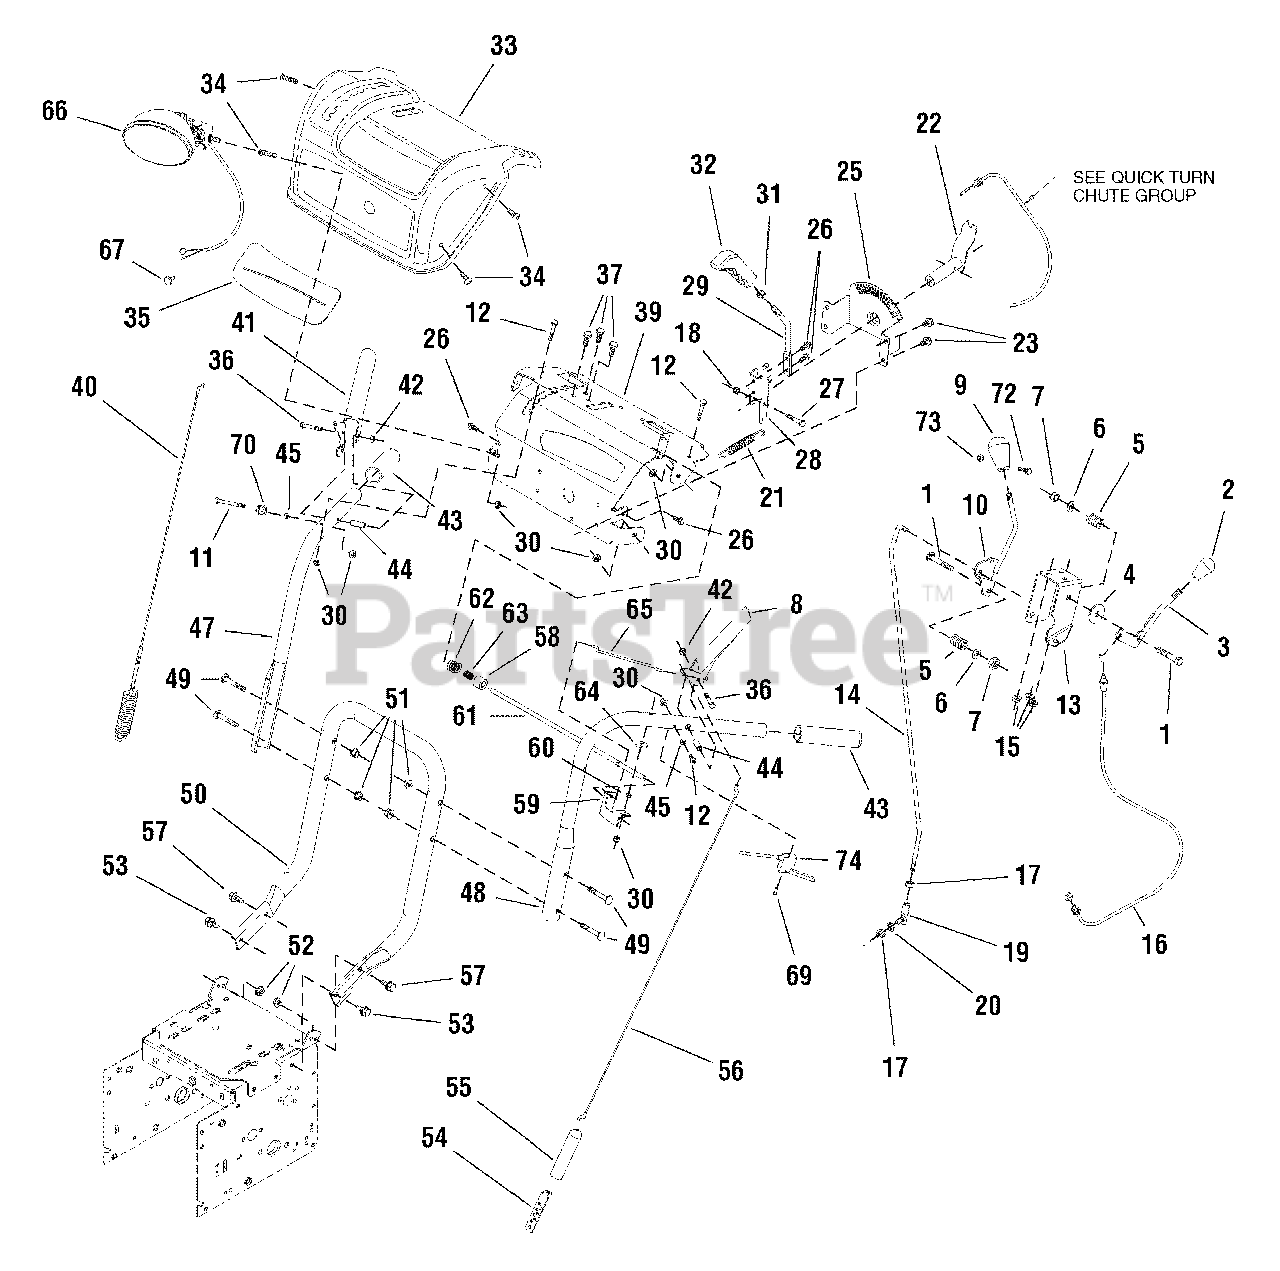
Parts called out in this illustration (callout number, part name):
1	CAPSCREW, Hex Head 3/8-16 x 2 G5
2	KNOB, Interior Thread 3/8-16
3	ROD, 3/8 Diameter 5" Large, 3/8-16 x 1 Chute
4	WASHER, 3/8
6	WASHER, 3/8
7	NUT, Hex Lock ESNA Light 3/8-16
8	HANDLE, Clutch L.H.
9	KNOB, Slot Speed
10	ROD & PLATE ASSEMBLY, Speed Control
11	CAPSCREW, Hex Head 1/4-20 x 2-1/2 G5
12	CAPSCREW, Hex Head 1/4-20 x 1-3/4 G5
13	BRACKET, Trac & Deflector Control
14	ROD
15	NUT, Hex Flange 5/16-18, Whiz Lock Small
16	CABLE, Deflector Control
17	NUT, Hex 5/16-24
18	NUT, Hex Flange 1/4-20 Centerlock Large
19	BALLJOINT, Steel
20	LOCKWASHER, Spring 5/16
21	SPRING, Extension
22	TUBE & BRACKET ASSEMBLY, Cable Support
23	SCREW, Hex Washer Head Taptite 5/16-18 x 1/2
25	SUPPORT, Chute Control 14GA
26	SCREW, Hex Washer Head Taptite 1/4-20 x 5/8
27	BOLT, Shoulder 1/4-20
28	BRACKET, Support Quick Turn
30	NUT, Hex Lock ESNA Light 1/4-20
31	NUT, Hex Jam 3/8-16
32	GRIP, Lever
33	COVER, Panel
34	SCREW, Truss Head Torx Drive 1/4-20 x 3/4
35	BELLOWS, Black Rubber Quick Turn
36	CAPSCREW, Hex Head 1/4-20 x 1-1/2 G5
37	CARRIAGE BOLT, 5/16-18 x 3/4 G5
39	SUPPORT, Dash Panel Cover
40	CABLE & SPRING ASSEMBLY, Auger Drive R.H.
41	HANDLE, Clutch R.H.
42	NUT, Hex Centerlock 1/4-20
45	SPACER
47	HANDLE, Upper R.H.
48	HANDLE, Upper L.H.
49	CARRIAGE BOLT, 5/16-18 x 2-1/4 G5
50	HANDLE, Lower
51	NUT, Hex Flange 5/16-18
52	NUT, Hex Flange 5/16-18 Two-Way Lock
53	SCREW, Hex Washer Head Taptite 5/16-18 x 3/4
54	BRACKET, Cable Adjusting
55	BOOT, Spring End Cover
57	CAPSCREW, Hex Head 5/16-18 x 1 G5
58	SPACER, Powdered Metal
59	BRACKET, Free Hand Control 12GA
60	SPACER, Powdered Metal
61	ROD & SPRING ASSEMBLY, w/Pin
62	WASHER, 1/2
63	SPRING, Compression
64	WASHER, 1/4
65	ROD, Hold Down E-Coat
66	HEADLIGHT ASSEMBLY, Oval Amber
67	FASTENER, Panel
69	SCREW, Pan Head Torx #10 x 1/2 Thick Cut
70	SPOOL CABLE, Auger Control
72	SCREW, Round Head Phillips #10-24 x 3/4
73	NUT, Hex Lock 10-24 w/Nylon Insert
74	CABLE & HANDLE ASSEMBLY
